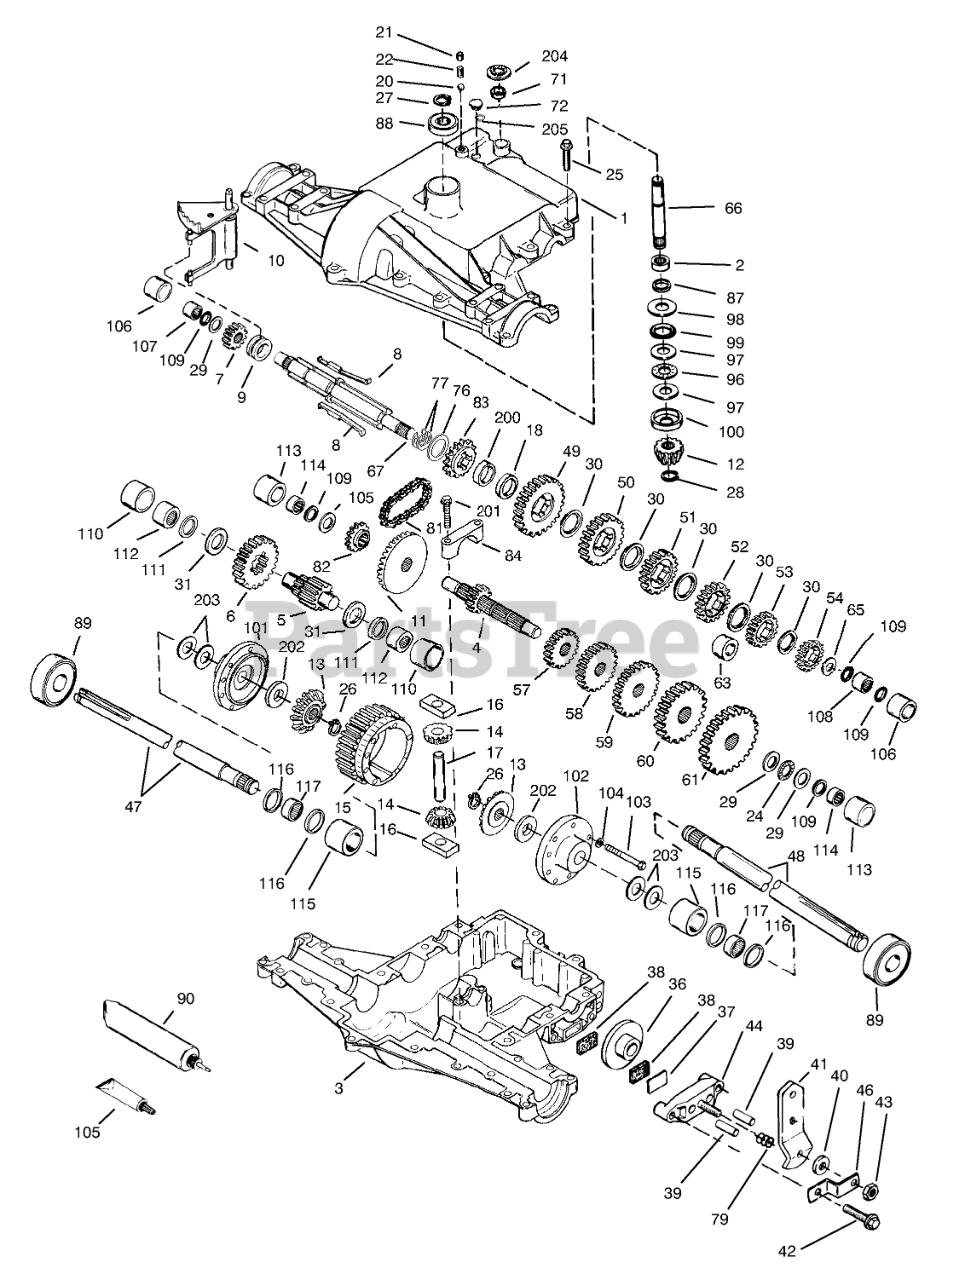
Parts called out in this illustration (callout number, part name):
1	Cover-Transaxle
2	Bearing-Needle
3	Case-Transaxle
4	Countershaft-Gear 9t
5	Shaft-Output
6	Gear-Output 35t
7	Gear-Spur 15t
8	Key-Shift
8	Key-Shift (820-024A Only)
9	Collar-Shift
9	Shift Collar
10	Fork-Shift
10	Fork-Shift (820-024A Only)
11	Gear-Bevel 33t
12	Pinion-Input 13t
13	Gear-Bevel
14	Pinion-Bevel
15	Gear-Ring
16	Biock-Drive
17	Pin-Drive
18	Spacer
20	Ball-Steel
21	Screw-Set
22	Spring
24	Bearing-Thrust
25	Screw 5/16-18x1 1/4
26	Ring-Snap
27	Ring-Snap
28	Ring-Retainer
29	Washer
30	Washer
31	Washer
37	Brake Pad Plate
38	Pad-Brake 2/Pkg
39	Dowel Pin
40	Washer
41	Lever-Brake
42	Ring Set (.020 O S)
43	Locknut
44	Nozzle-Carburetor
46	Bracket
47	Axle 12 9/16" Long
48	Axle 16 7/16" Long
49	Gear-Spur 41t
50	Gear-Spur 35t
51	Gear-Spur 30t
52	Gear Spur 25t
53	Gear Spur 22t
54	Gear Spur 19t
57	Gear Spur 15t
58	Gear Spur 20t
59	Gear Spur 25t
60	Gear Spur 28t
61	Gear Spur 30t
65	Washer
66	Shaft-Input
67	Shaft-Shifter/Brake
67	Shaft-Shifter/Brake (820-024A Only)
71	Cut Seal-Square
72	Plug-Threaded 5/16-18
76	Washer
77	Inverted Retaining Ring
79	Piston ASM (.020 O S)
81	Chain-Roller
82	Sprocket 10t
83	Sprocket (14 teeth)
84	Cap-Bearing
87	Seal Oil
88	Bearing-Ball
89	Bearing-Ball
90	Grease 32 Oz
96	Bearing-Thrust
97	Washer
98	Washer
99	O Ring
100	Washer-Cupped
101	Carrier-Differential
102	Carrier-Differential
103	Screw-Hex Hd.
104	Lockwasher
105	Washer
106	Sleeve
107	Bearing-Needle
108	Bearing-Needle
109	O Ring
110	Sleeve
111	Ring-Square Cut
112	Bearing-Needle
113	Sleeve
114	Bearing-Needle
115	Sleeve
116	Ring-Square Cut
117	Bearing-Needle
150	Gasket Eliminator
200	Spacer
201	Ring Set (.020 O S)
202	Washer
203	Washer
204	Pushnut
205	O Ring
